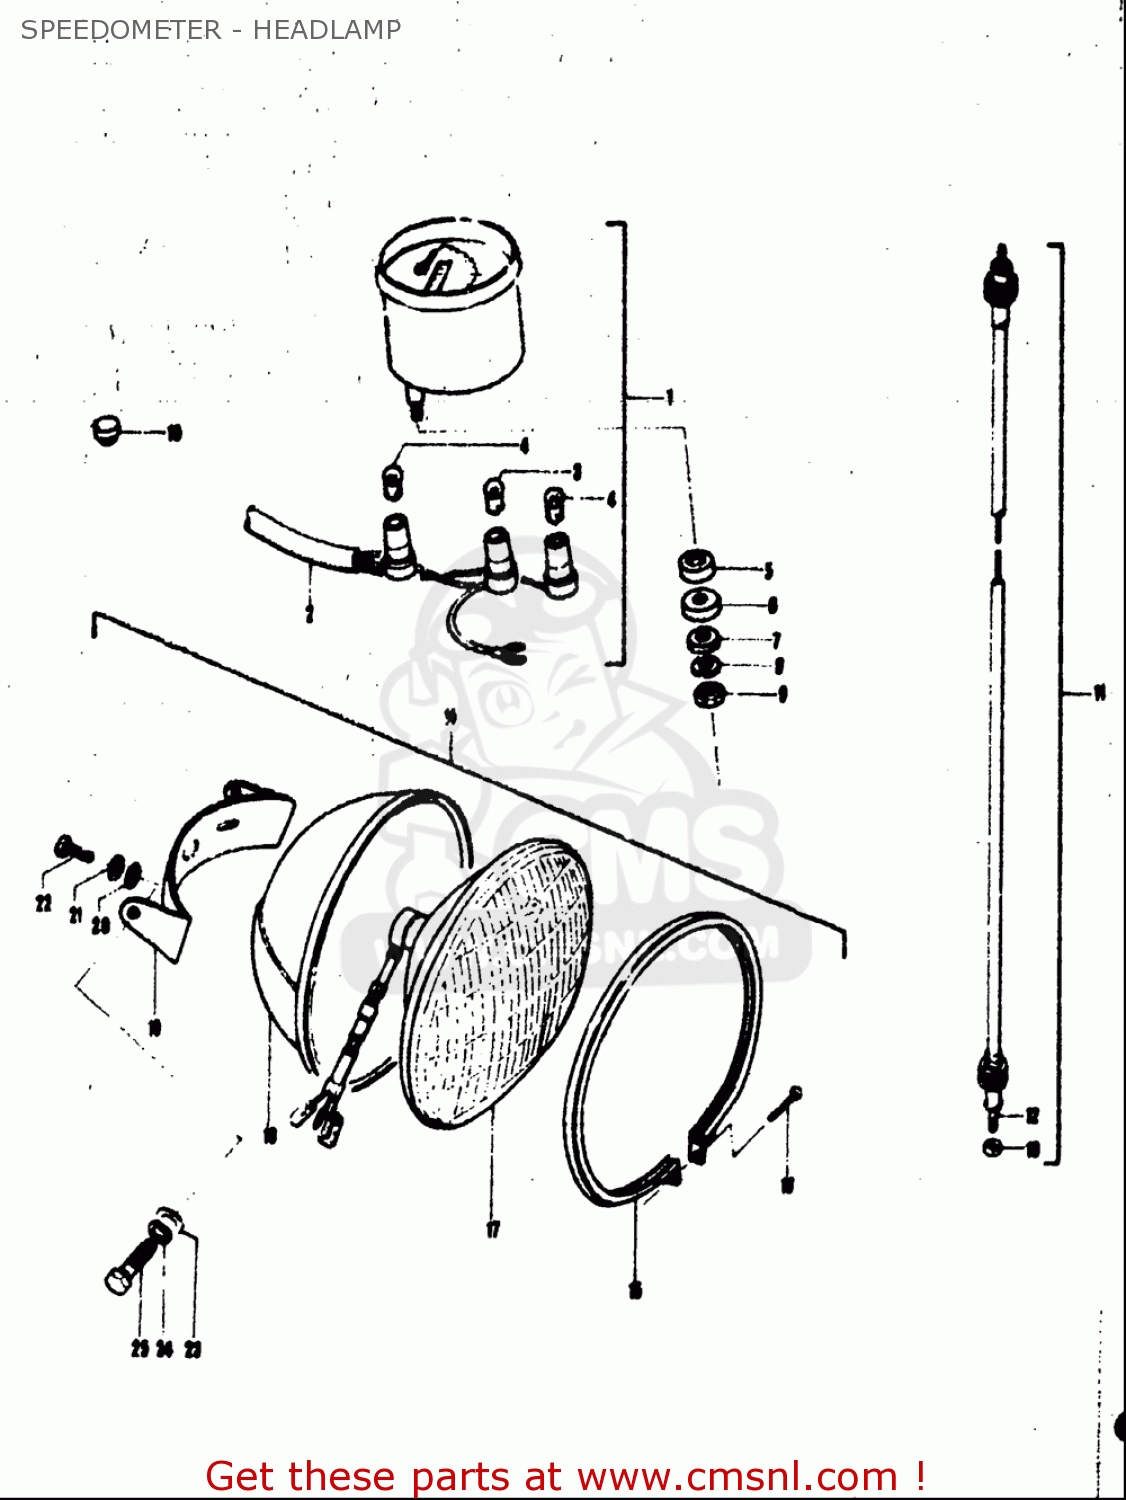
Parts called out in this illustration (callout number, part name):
3	BULB(6V1.7W,STANLEY,A61A)
4	BULB(6V/3W)
5	CUSHION,METER
6	CUSHION
7	WASHER (5.5X18X1.6)
8	WASHER,LOCK
9	NUT
13	SEAL,OIL METER CABLE
20	WASHER
21	WASHER,LOCK
23	WASHER
24	WASHER,LOCK
